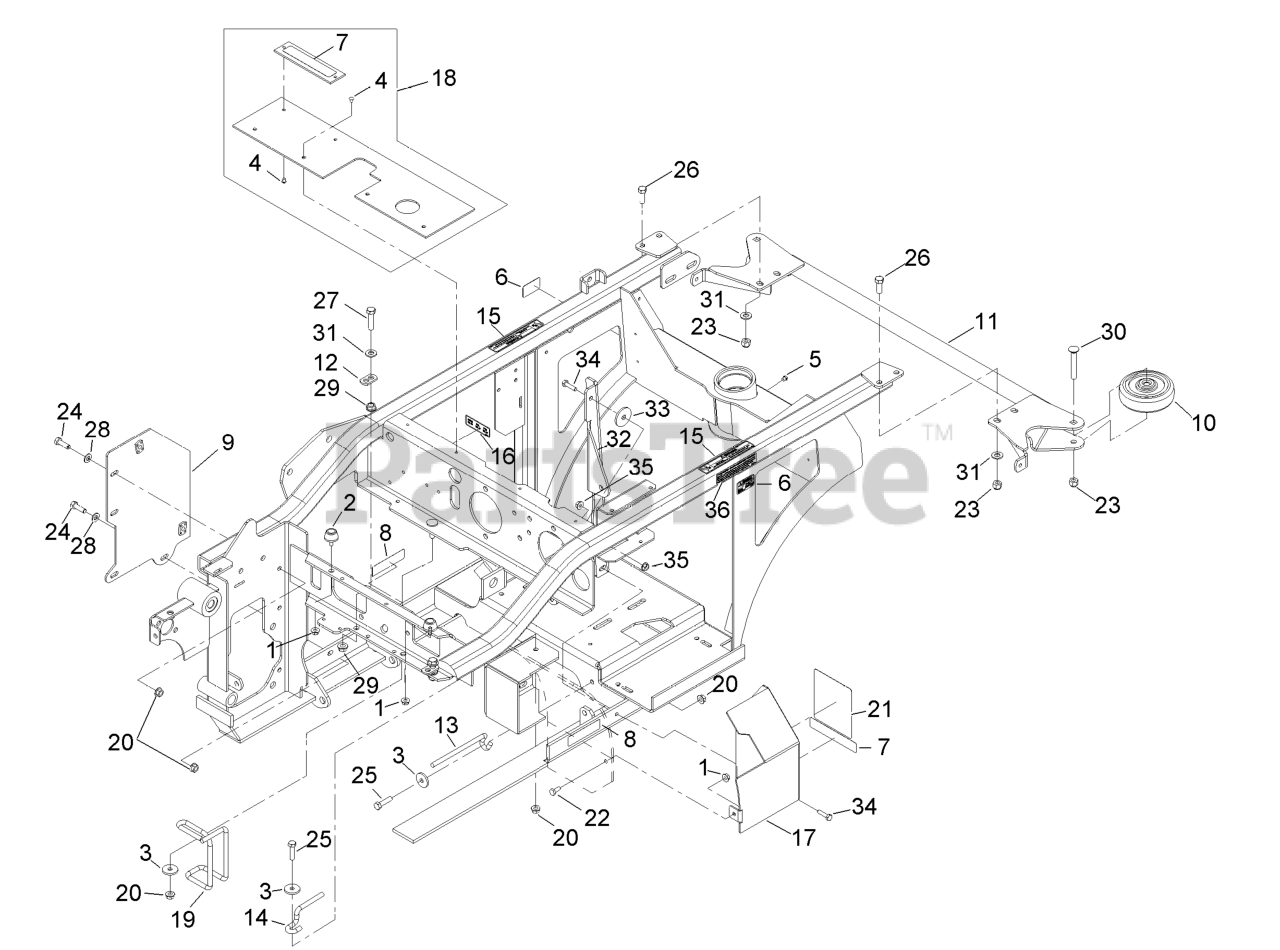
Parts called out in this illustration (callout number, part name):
2	BUMPER-RUBBER
4	RIVET-POP
6	DECAL-SURFACE, HOT
7	DECAL-WARNING
8	DECAL-COVER, MISSING
9	WLD,FENDER (RAW)
10	ROLLER-BUMPER
11	BUMPER-REAR
12	TAB,SPRING ANCHOR
13	GUIDE-BELT
14	GUIDE-BELT
15	DECAL,PINCH POINT
16	DECAL,RELAY
18	LIFT SHIELD ASM
19	GUIDE,BELT (PLATED)
21	DECAL,BELT ROUTING
22	SCREW-HH
23	NUT-LOCK, NI
24	SCREW-HH
25	SCREW-HH
26	SCREW-HH
27	SCREW-HH
28	WASHER-PLAIN
29	NUT-HHF, WHIZ
30	SCREW-CARR
31	WASHER-FLAT
32	BRACE-PTO
34	SCREW-HH
36	DECAL-ARRESTER, SPARK
